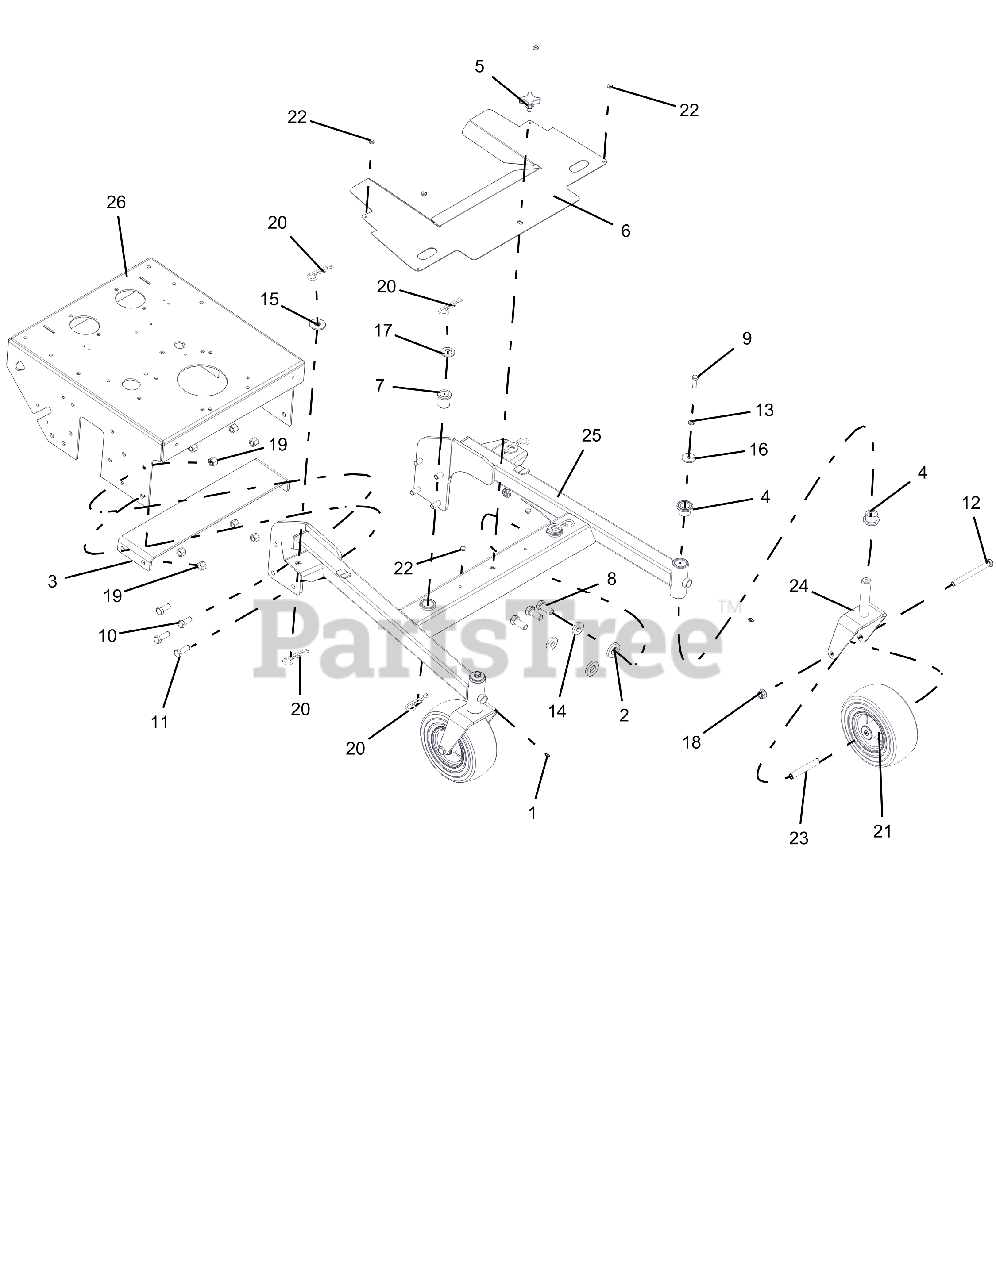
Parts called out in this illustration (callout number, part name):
1	FTG, 1/4-28 STRGT GREASE ZERK
2	WSHR-FL-STL .905X1.750X.25 YWZC
3	PLATE, ENGINE BED FRONT 48/52-RED
4	BRG, FLANGE 1.00 X 1.25 X 1.00
5	KNOB, 3/8-16 x .75
6	SHIELD, BELT 48" HYDRO WALK
7	BSHG-FLG 1.00X1.25X1.5X1.5
8	BLT-HEX .62-11X1.50 GR8 YWZC
9	BLT-HEX .38-16X1.25 GR5 YWZC
10	BLT-HEX .50-13X1.25 GR5 YWZC
11	BLT-HEX .50-13X1.50 GR5 YWZC
12	BLT-HEX .50-13X5.50 GR5YWZC
13	WSHR-LK .38X.094 REG YWZC
14	WSHR-FL-STL .630X1.50X.25 YWZC
15	WSHR-FL-STL.688X1.75X.134 YWZ
16	WSHR-FL-STL .380X1.50X.125 YWZC
17	WSHR-FL-STL .875X1.500X.1196YZ
18	NUT-LK-NYL-FLG .50-13 YWZC
19	NUT-LK-NYL .50-13 YWZC
20	PIN-HAIR-INT .17X.68X3.50 YWZC
21	9X3.5-4 CAREFREE BLT TOGETHER
22	BUMPER GROMMET .125 X .25 REV
23	TUBE, CASTER AXLE
24	WLDMT, FRONT WHEEL FLOAT WALK
25	WLDMT, DECK FRAME 48 FLWLK
26	WLDMT, ENGINE
